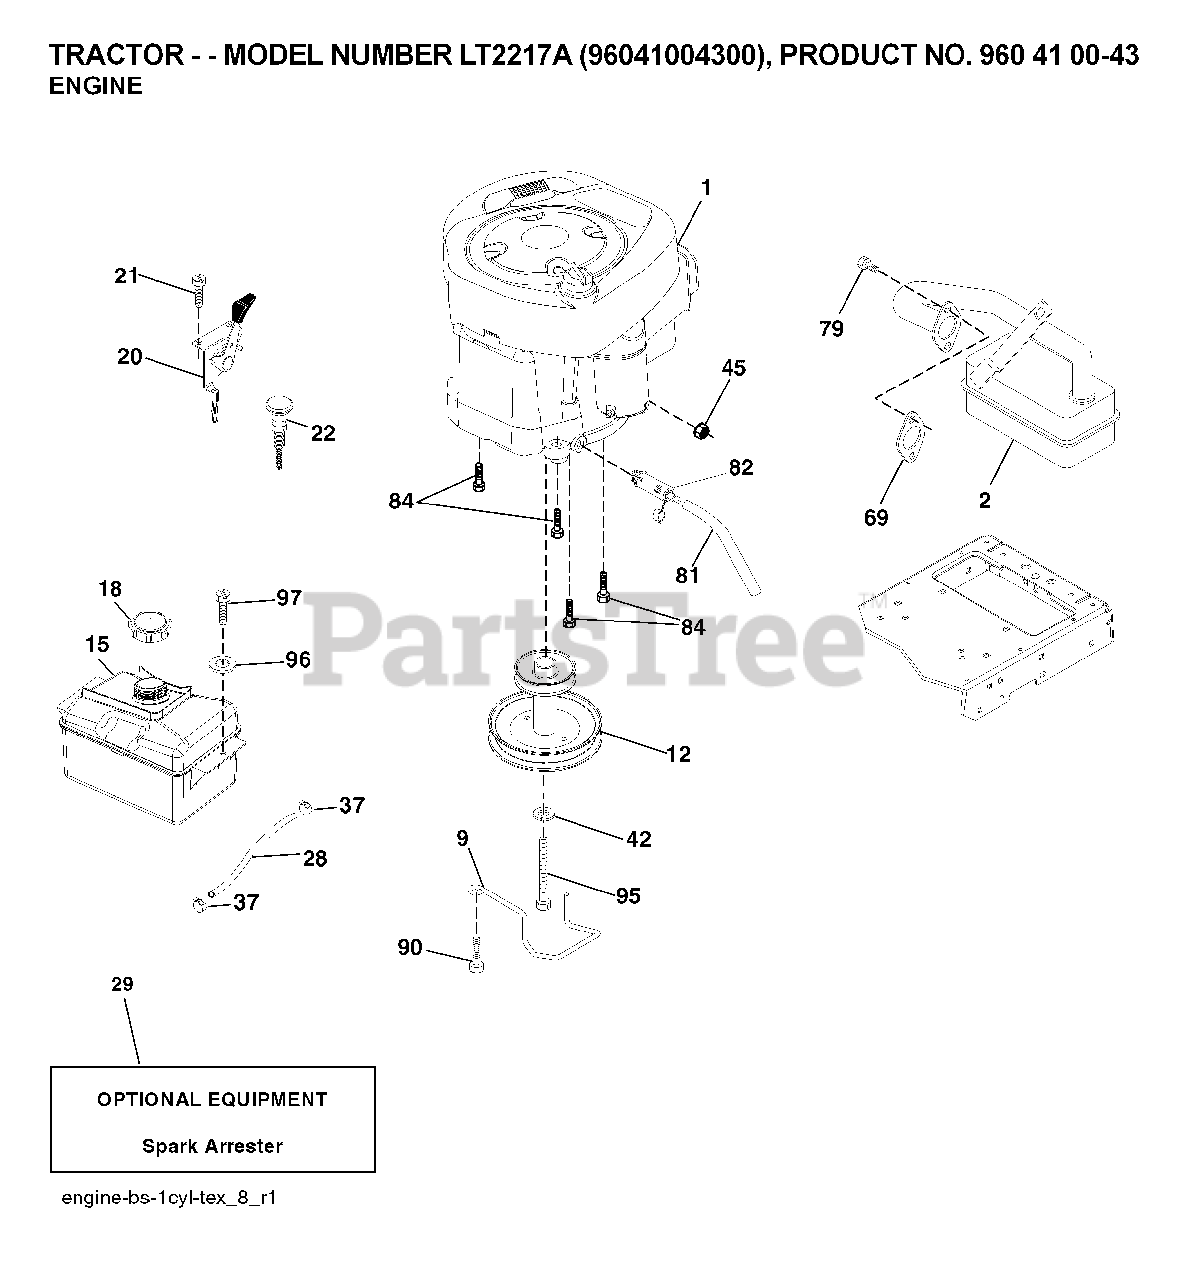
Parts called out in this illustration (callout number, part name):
9	KEEPER.BELT.ENGINE.3.25
12	PULLEY ENGINE
15	TANK FUEL FRT 1.5 GAL
18	FUEL CAP
20	CONTROL.TH/CK.C.
21	SCREW
28	LINE.FUEL.20
29	ARRESTER SPARK (OPTIONAL)
37	HOSE CLAMP
42	LOCKWASHER
45	NUT
69	REPL BY 532 27 22-93
79	SCREW.SOCKET HD.5/16-1
81	TUBE, DRAIN OIL ASM.
82	PLUG DRAIN OIL EASY
84	SCREW.3/8-16
90	SCREW 3/8-16X1
95	BOLT HEX 7/16-20X4-1/4"
97	SCREW HEXWSHR 1/4-20X3/4
